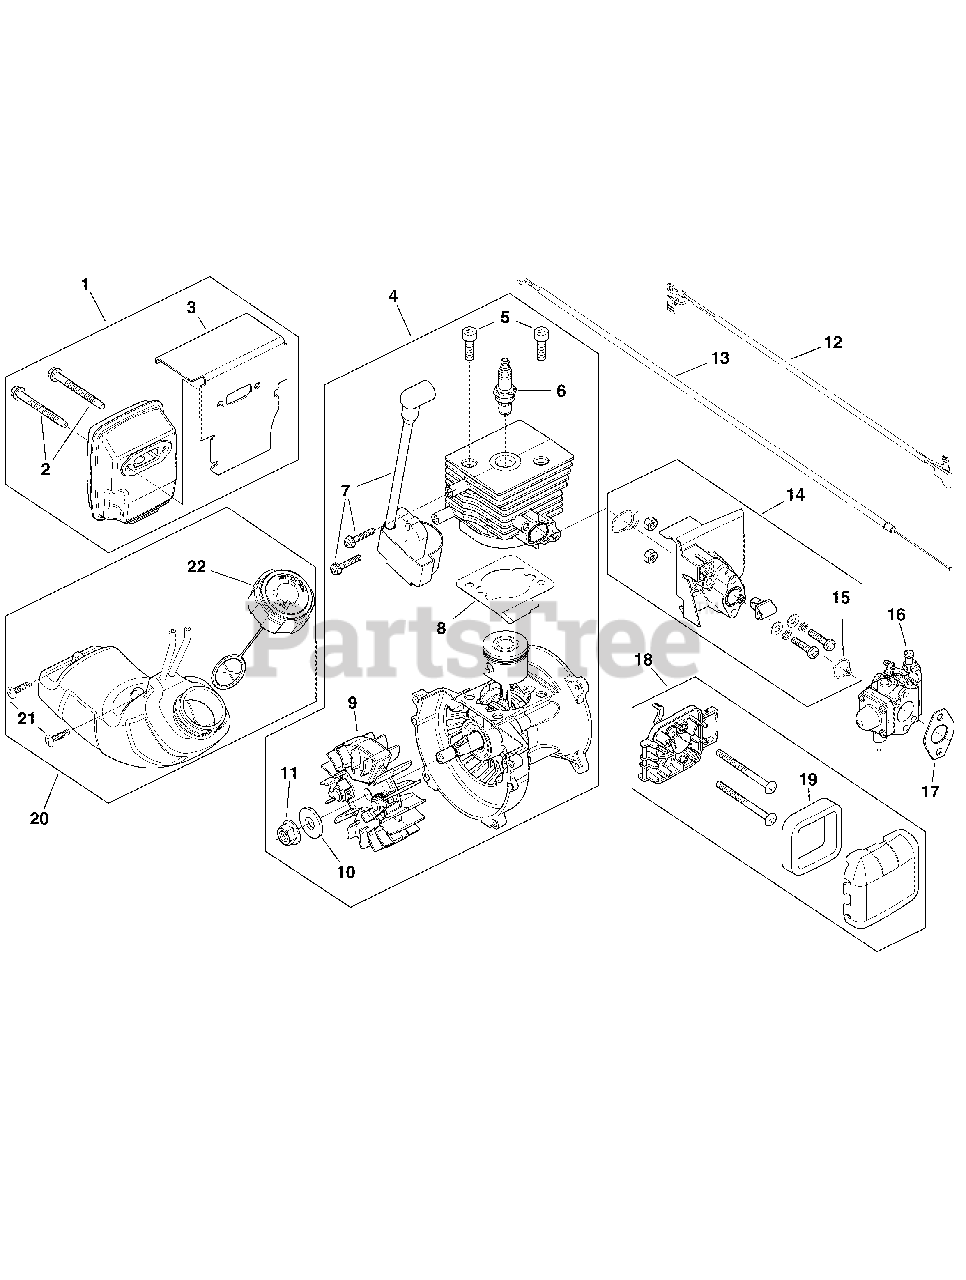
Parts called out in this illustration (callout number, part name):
1	ASSEMBLY, Muffler
2	SCREWS, Muffler
3	GASKET, Muffler
4	ASSEMBLY, Shortblock
5	BOLT, Cylinder
6	Spark Plug
7	Module Assembly
8	GASKET, Cylinder
9	ASSEMBLY, Flywheel
12	WIRE, Lead
13	CABLE, Throttle
14	Insulator Assembly
15	O-RING, Insulator
16	ASSEMBLY, Carburetor
17	Carburetor Gasket
18	Air Cleaner Assembly
19	Air Filter
20	ASSEMBLY, Fuel Tank
22	Fuel Cap
